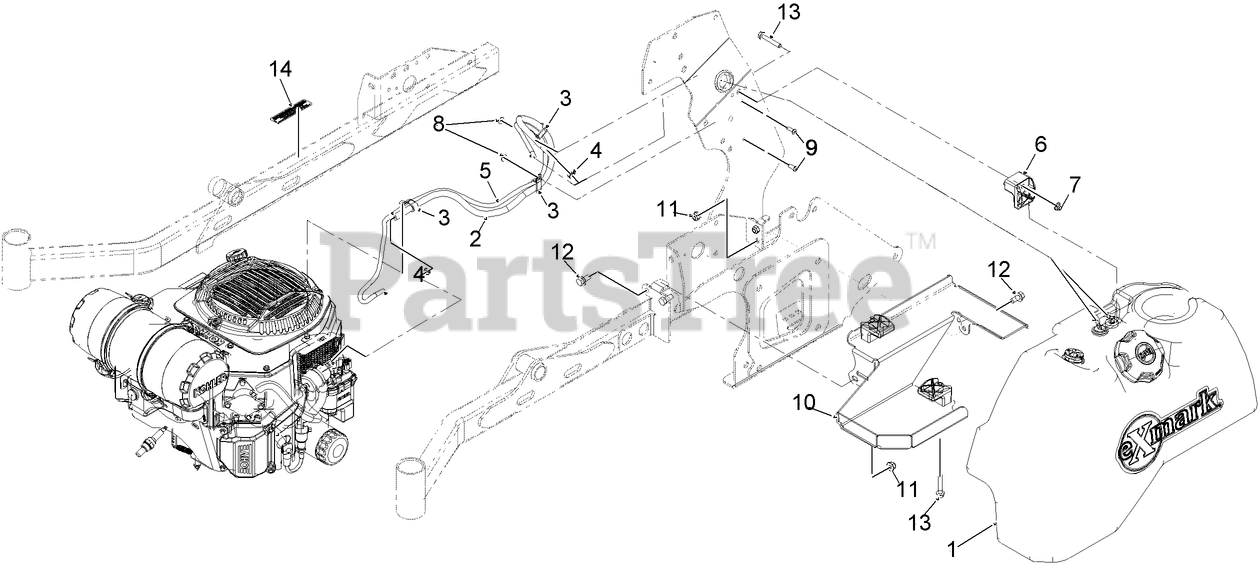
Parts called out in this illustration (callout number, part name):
1	ASM, FUEL TANK 8 GAL
2	HOSE-FUEL
3	CLAMP-R, DOUBLE TUBE
4	CLAMP-HOSE
5	HOSE-EMISSIONS
7	NUT-HF, NI
9	SCREW-HSBH
10	Bracket, Fuel Tank
11	NUT-HF, NI
12	Screw-HH Flg 3/8-16 X 3/4
13	SCREW-HHF
14	DECAL-ARRESTOR, SPARK
